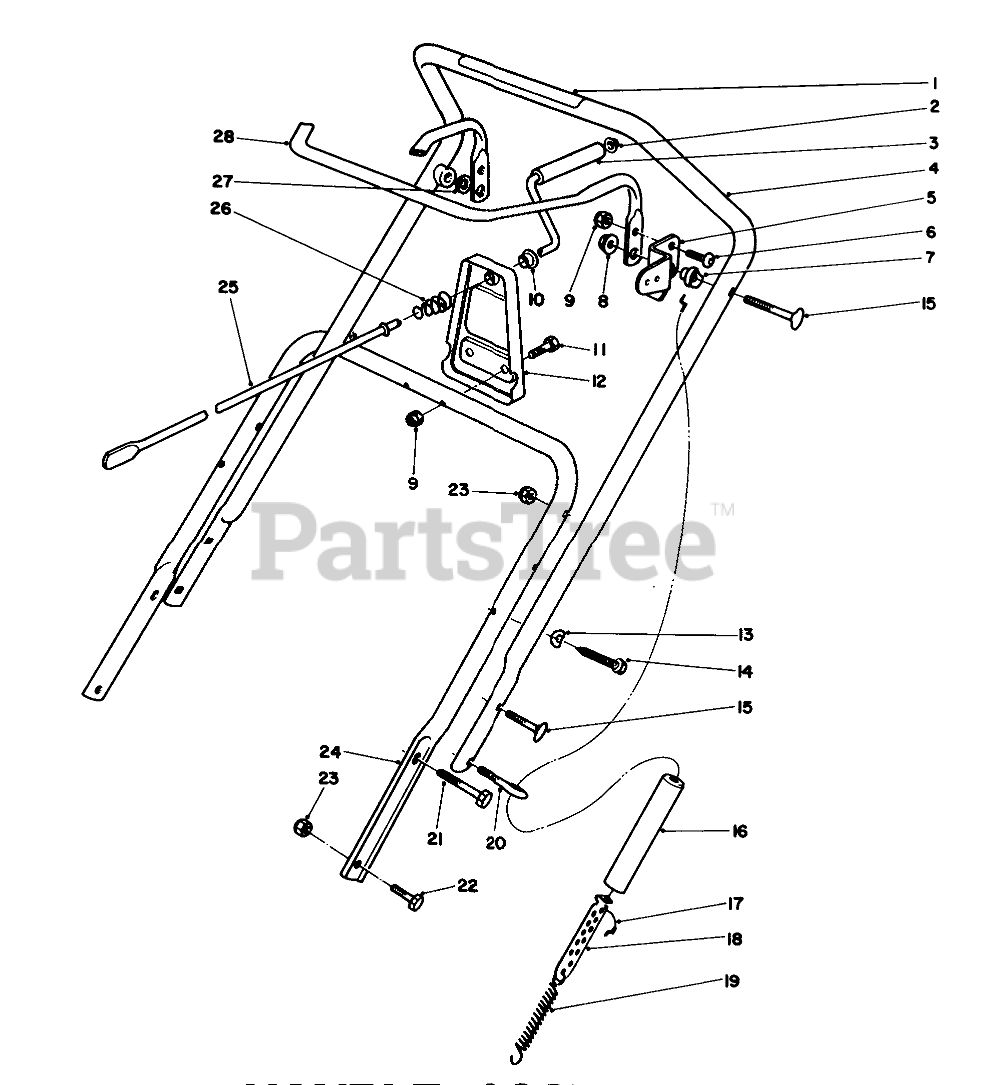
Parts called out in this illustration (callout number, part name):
1	DECAL - ROTOR DRIVE
2	ROTOR DRIVE DECAL
2	RETAINER-PUSH ON
3	Grip-Rod
4	Upper Handle Assembly (Incl. Ref. #1: 66-6870)
5	Arm-Clutch Cable
6	SCREW-HSBH
7	SPACER-BAR, CONTROL
8	NUT-LOCK, CAP
9	NUT-LOCK, NI
10	Bushing
11	SCREW-HH
12	Support-Crank
13	WASHER
14	SCREW
15	SCREW
16	COVER-SPRING
17	CABLE-CLUTCH
18	ADJUSTER-CABLE
19	SPRING-EXTENSION
20	BOLT-EYE
21	SCREW-HH
22	SCREW-HH
23	NUT-LOCK, NI
24	LOWER HANDLE
25	ROD-CRANK, CHUTE
26	SPRING-COMPRESSION
27	WASHER
28	Bar-Control
